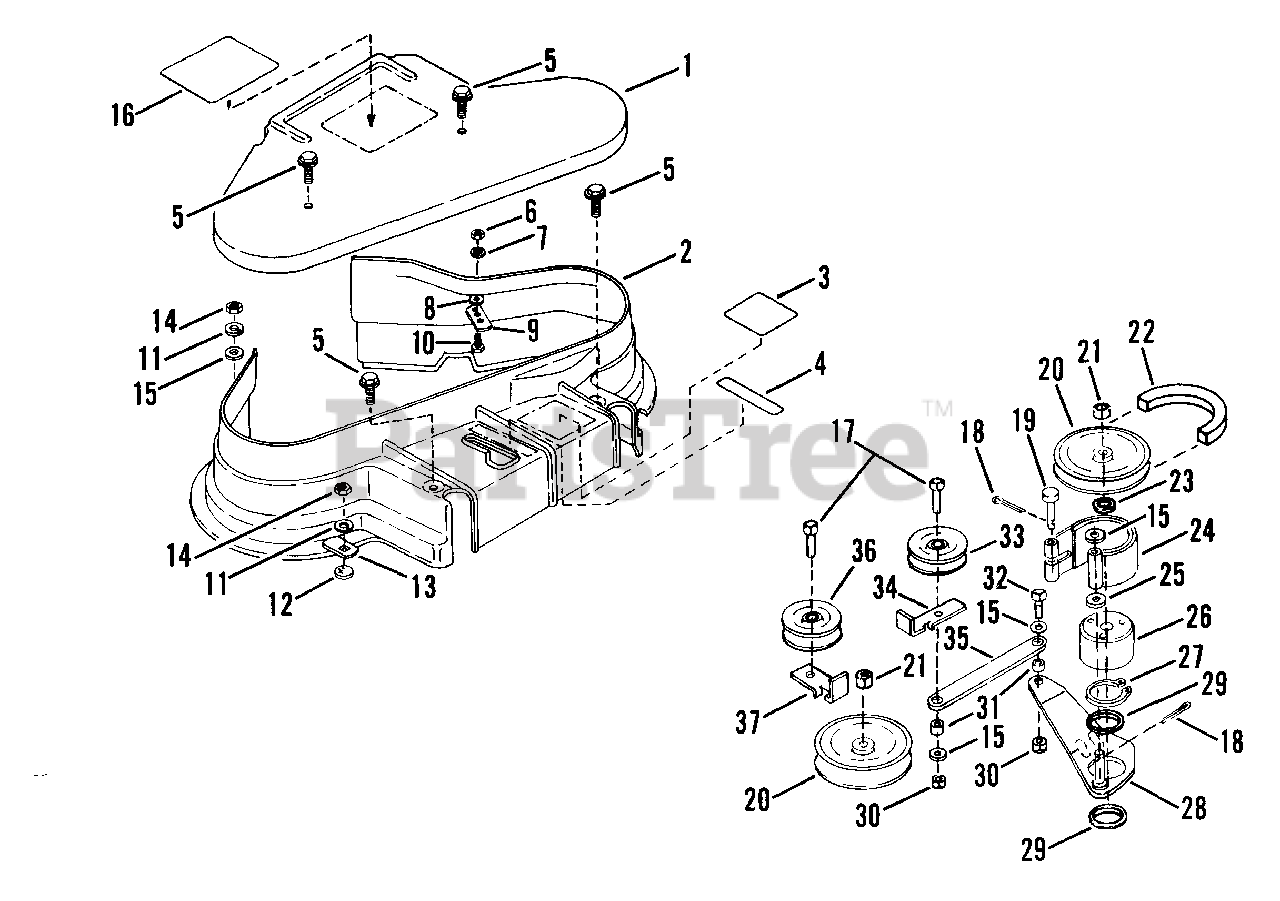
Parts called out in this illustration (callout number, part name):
1	ASSEMBLY, 41" Cover (Top)
2	ASSEMBLY, 41" Cover (Bottom)
3	DECAL, Brake Operation
4	DECAl, Blade (ON-OFF)
5	SCREW, 1/4-28 x 5/8" Self-Tap
6	NUT, 1/4-20 Hex
7	WASHER, 1/4 Internal Tooth Lock
8	WASHER, 1/4 Flat
9	GUIDE, Belt
10	SCREW, 1/4-20 x 1/2" Hex Cap
11	WASNER, 3/8 Split Lock
12	RETAINER, 3/8 Bolt
13	CLIP
14	NUT, 3/8-16 Hex
15	WASHER, 3/8" Flat
16	DECAL, Caution
17	SCREW, 3/8-24 x 1-3/4" Hex Cap
18	PIN, 3/32 x 3/4" Cotter
19	PIN, 1/4 Clevis
20	PULLEY, 5" O.D.
21	NUT, 3/4-16 Hex Jam Lock
22	BELT, AA105
23	WASHER, 3/4 Flat
24	BAND, Brake Assembly
25	SPACER
26	BRAKE DRUM
27	RING, 2" External Retaining
28	ASSEMBLY, Brake Arm
29	WASHER, 2" I.D.
30	NUT, 3/8-24 Hex Lock
31	SPACER
32	SCREW, 3/8-24 x 3/4" Hex Head Cap
33	PULLEY, Idler
34	RESTRICTOR
36	PULLEY, Idler
37	GUIDE, Belt
